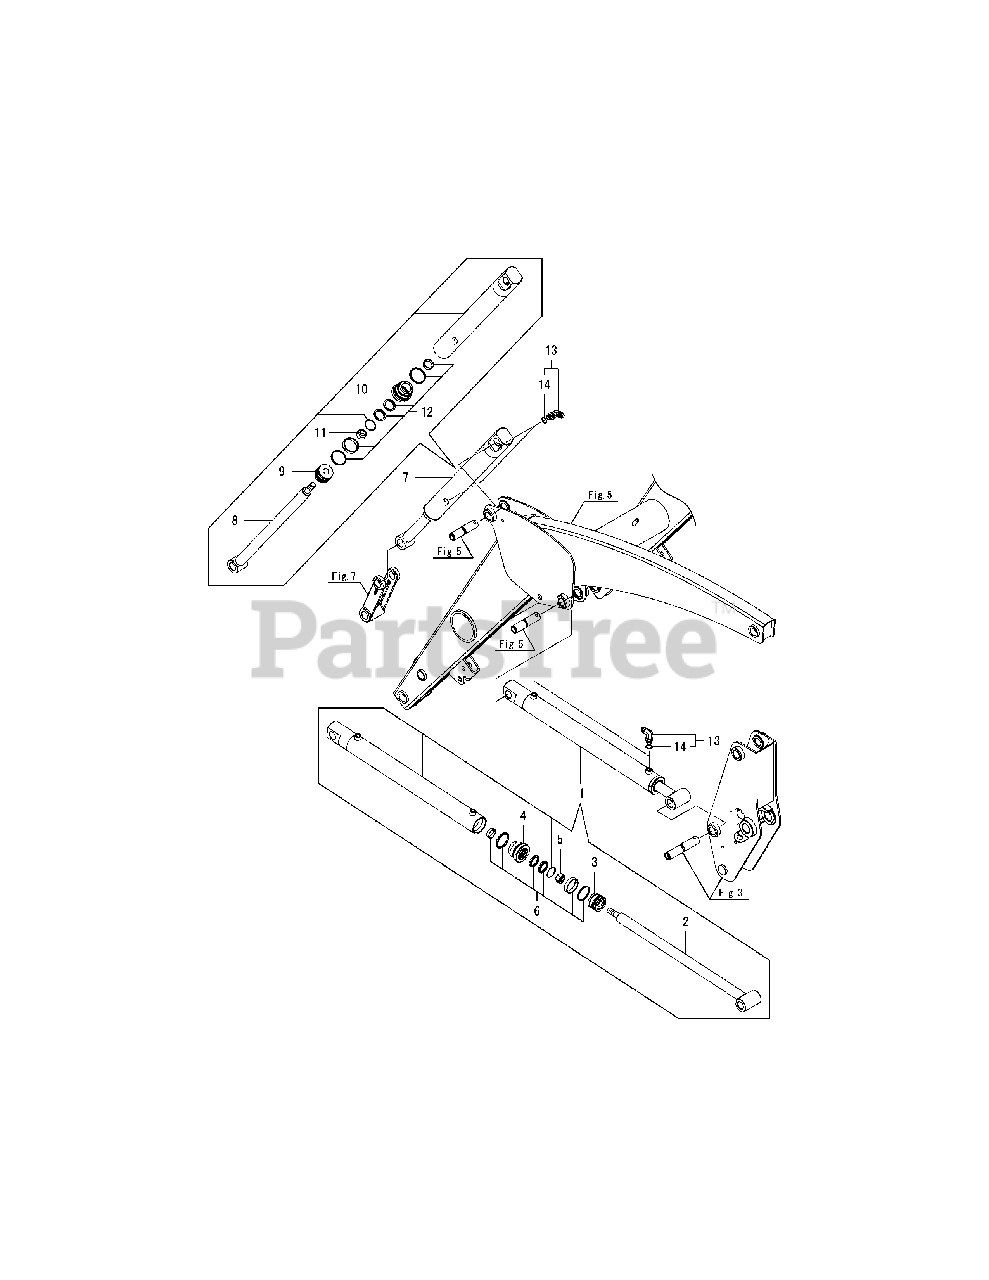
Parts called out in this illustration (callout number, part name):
1	LIFT CYLINDER ASSY
2	WELDED ROD CPL, LIFT
5	SELF LOCKING NUT
7	DUMP CYLINDER ASSY
8	WELDED ROD CPL, DUMP
11	SELF LOCKING NUT
13	JOINT,90SAE9/16-18
14	PACKING, JOINT
